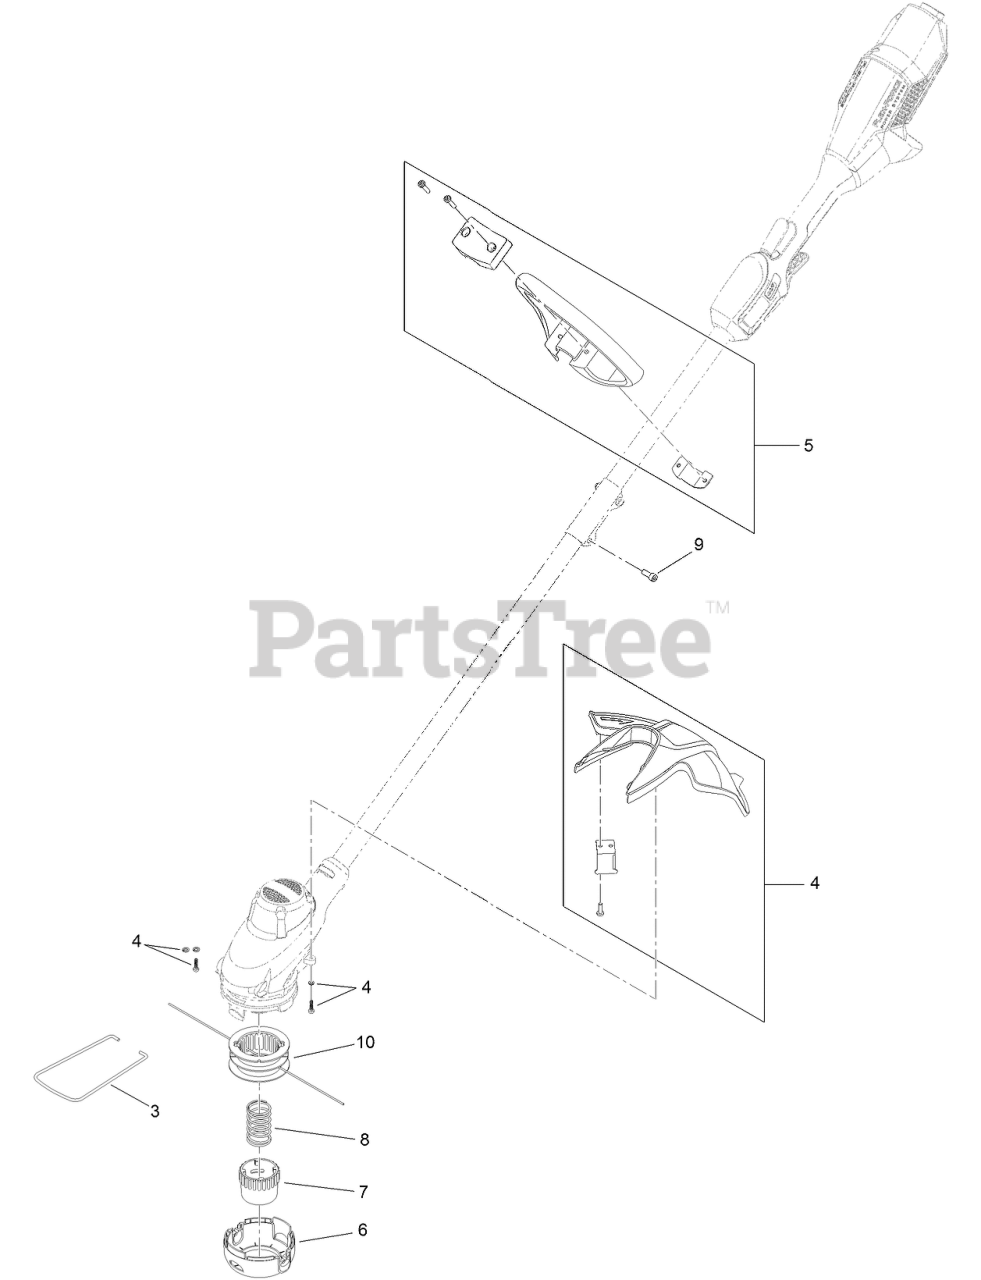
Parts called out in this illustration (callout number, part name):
3	GUIDE-TRIMMER
4	GUARD ASM
5	HANDLE-TRIMMER
6	COVER-SPOOL
7	BUTTON-FEED, BUMP
8	SPRING-FEED, BUMP
9	SCREW-COUPLER, SHAFT
